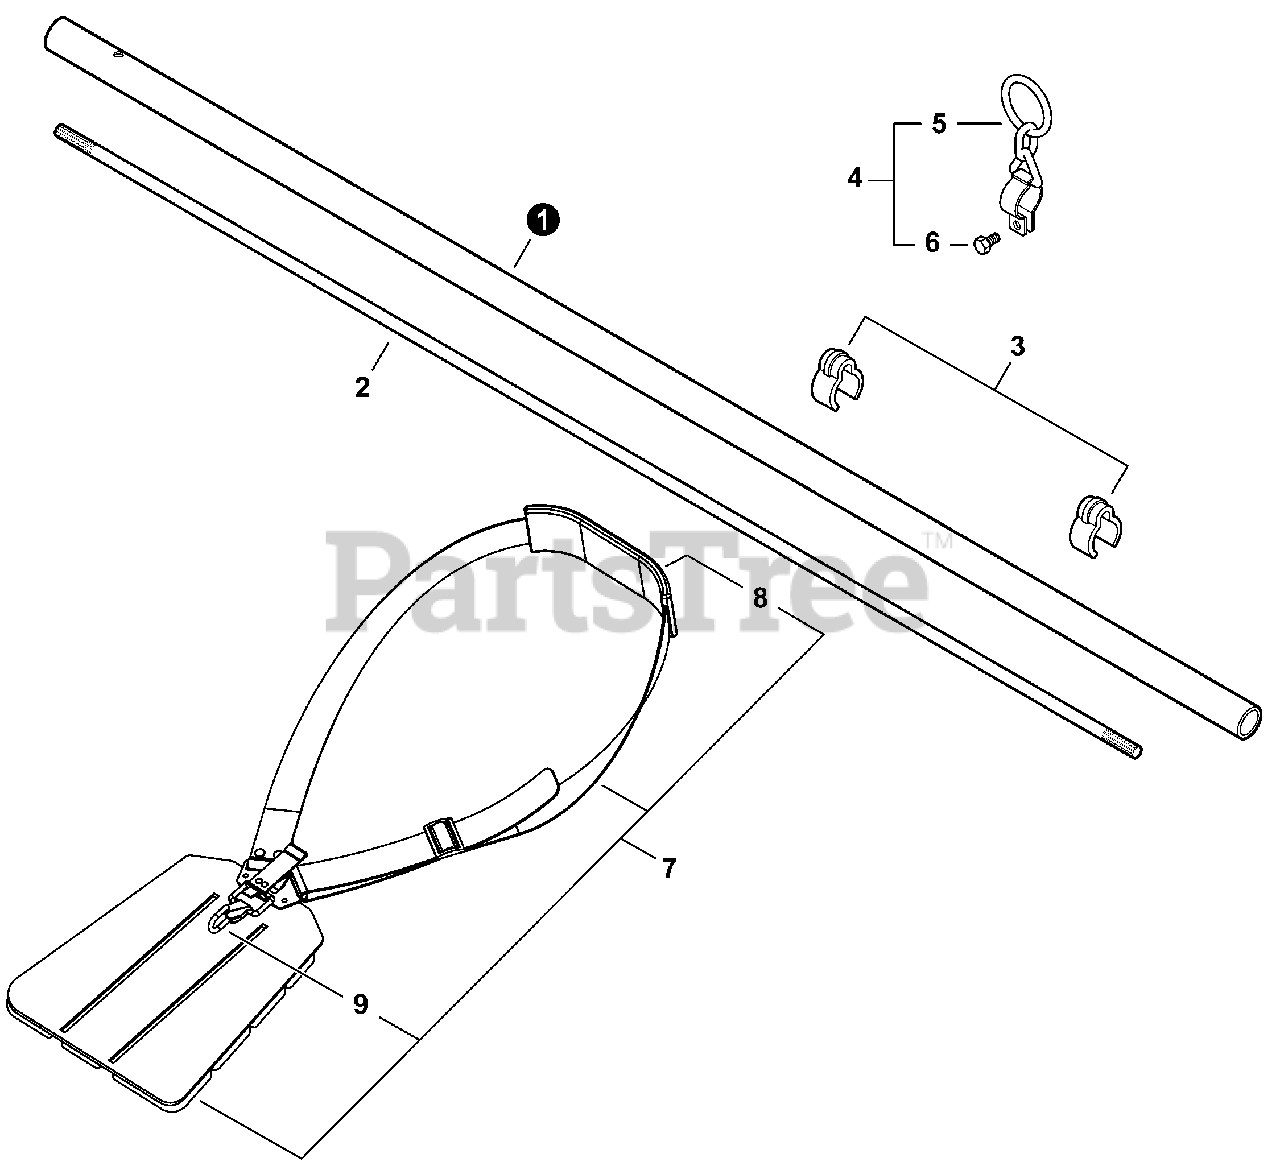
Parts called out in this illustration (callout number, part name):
1	PIPE, MAIN
2	MAINSHAFT
3	CLIP, CABLE 25 MM
4	HANGER SET, HARNESS
5	HANGER SET, HARNESS
6	BOLT 5×12
7	HARNESS ASSY, BRUSHCUTTER
8	PAD, SHOULDER
9	HOOK, SNAP
